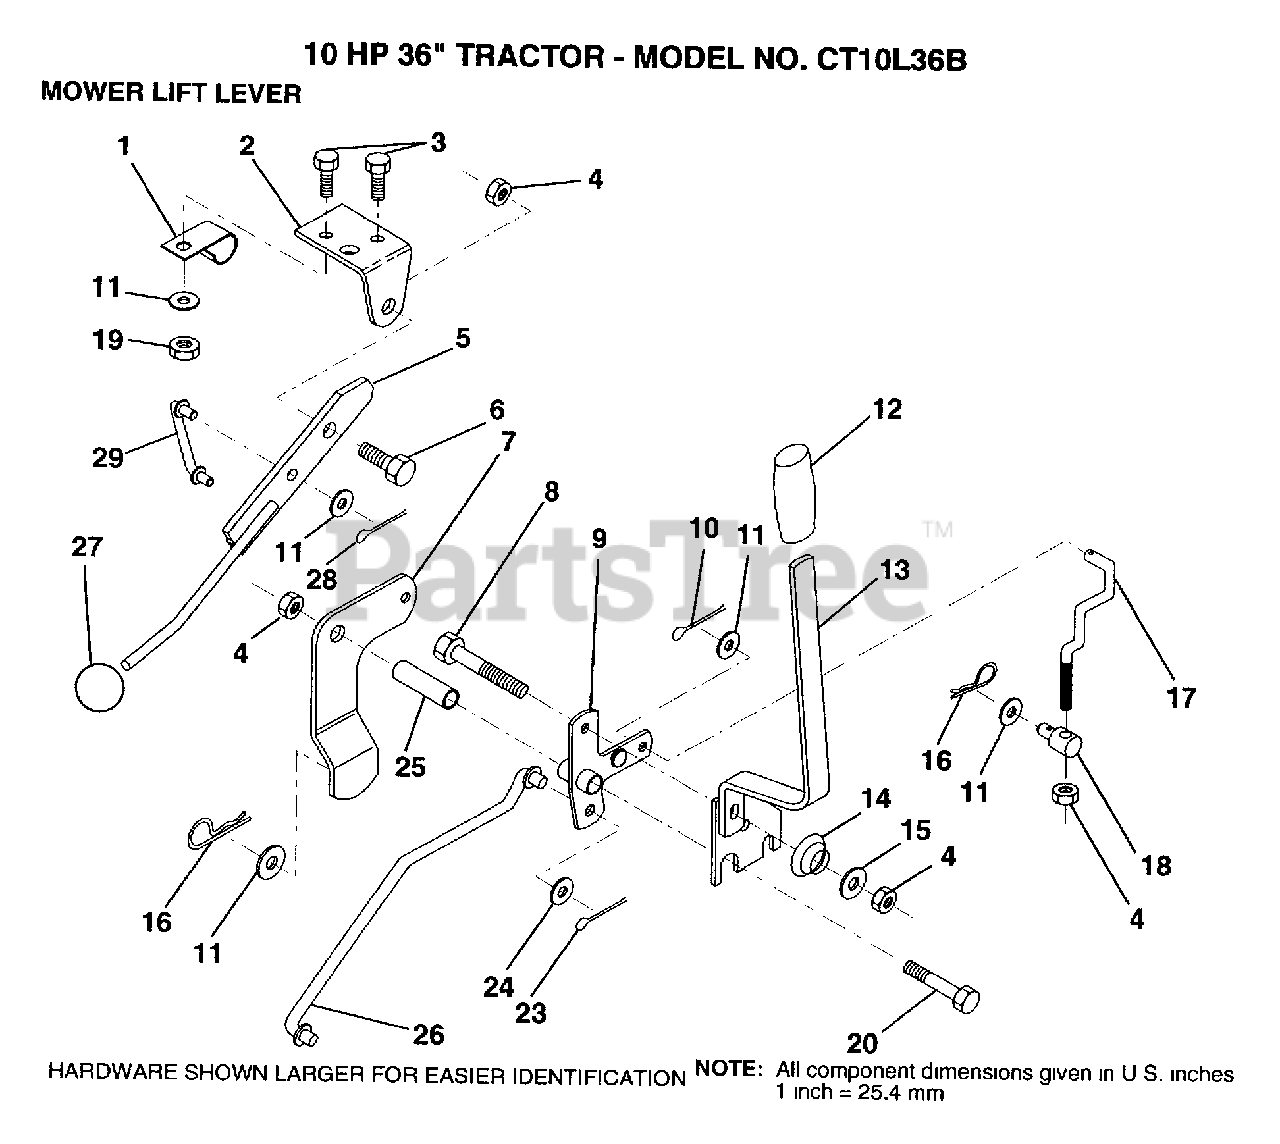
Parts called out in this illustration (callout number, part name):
1	"CLIP,INSULATOR"
2	BRKT CLUTCH
3	BOLT
5	CLUTCH LEVER AS
6	"BOLT, SHOULDER LT"
7	MWR CLUTCH ARM AS
8	BOLT
9	"BELLCRANK,LIFT"
10	COTTER PIN
11	WASHER
13	"HDLE,LIFT T"
14	SPRING COMPRESSIO
15	WASHER T
16	SPRING.RETAINER
17	"LINK,LIFT FRT"
18	TRUNION
20	BOLT
23	PIN COTTER 1/8
25	TUBE SPACER
26	"ROD,MOWER LIFT "
27	KNOB T(3/8 HOLE)
29	CLUTCH LINK
